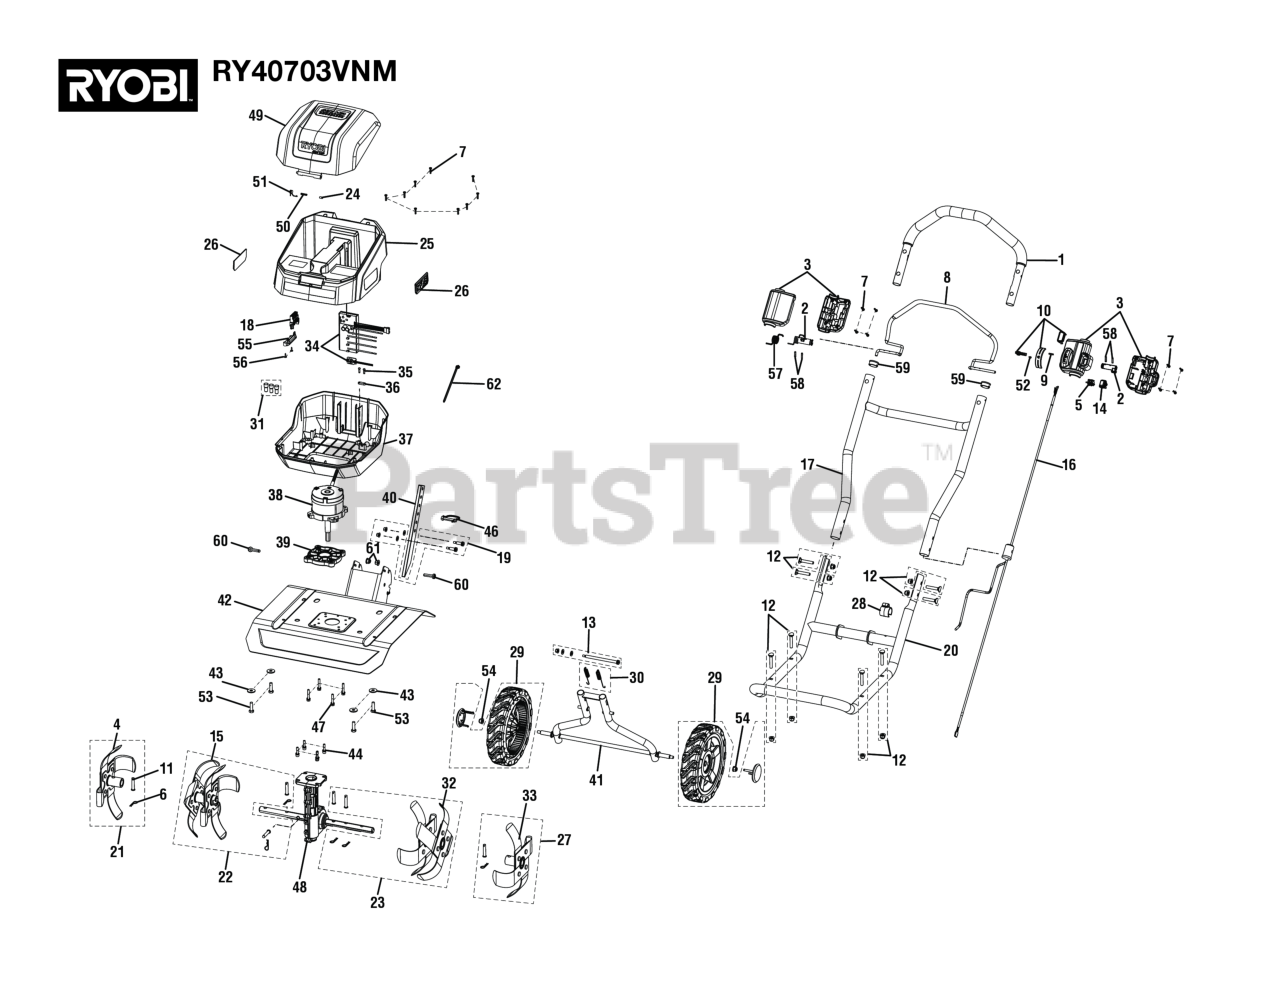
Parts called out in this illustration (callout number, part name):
1	Foam and Upper Handle Assembly
2	Tine Blade Assemby (Outer Right)
3	Tine Blade Assembly (Inner Right)
4	Tine Blade Assembly (Outer Right)
5	Bail Switch
6	Cotter Pin
7	Screw (M4 x 18 mm, T20 Torx Pan Hd. S.T.)
9	Dial Lever Insert
10	Tine Blade Assembly (Outer Left)
12	Handlebar Bolt and Nut Assembly
13	Pivot Bolt Assembly
14	Center Switch
15	Tine Blade (Inner Right)
16	Main Wire Assembly
17	Middle Tube
18	Battery Contact Holder Assembly
19	Drag Stake Bolt Assembly
20	Lower Tube
21	Bail Switch
22	Right Actuator Assembly
23	Tine Blade Assembly
24	Battery Door Axle
25	Battery Bucket
26	RYOBI Logo Badge
27	Left Actuator Assembly
28	Cord Retainer
29	10 in. Wheel Assembly
30	Tension Spring
31	Wire Connector
32	Tine Blade (Inner Left)
33	Tine Blade (Outer Left)
34	Motor Controller and Circuit Board Assembly
35	ST SCREW,STEEL CH M4.0X1.8 PH TORX
36	Wire Press Plate
37	Battery Base
39	Cushion Block
40	Drag Stake
41	Wheel Axle Adjust Bracket
42	Tine Shield
43	Washer (OD25.2 x ID8.6 x 2.5t)
44	Screw w/Washer (M6 x 25 mm, Rd. Hd. )
45	Tine Blade Assembly (Outer Right)
46	Spring Pin
47	Screw with Spring Washer (M6 x 35 mm)
48	Gear Box Assembly
49	Battery Cover
50	Compression Spring
51	Battery Door Torsion Spring
52	Screw (M x 12 mm, Pan Hd.)
53	Screw (M8 x 30 mm, Hex Hd.)
54	Lock Nut (M8 x 1.25 mm, Flange)
55	Pressing Plate
56	Screw (M4.2 x 12 mm, T20 Torx Pan Hd.)
57	Torsion Spring
58	Spring Pin
60	Bolt (M5 x 14 mm)
61	Flange Lock Nut (M5 x 0.8 in.)
62	NYLON CABLE TIE
